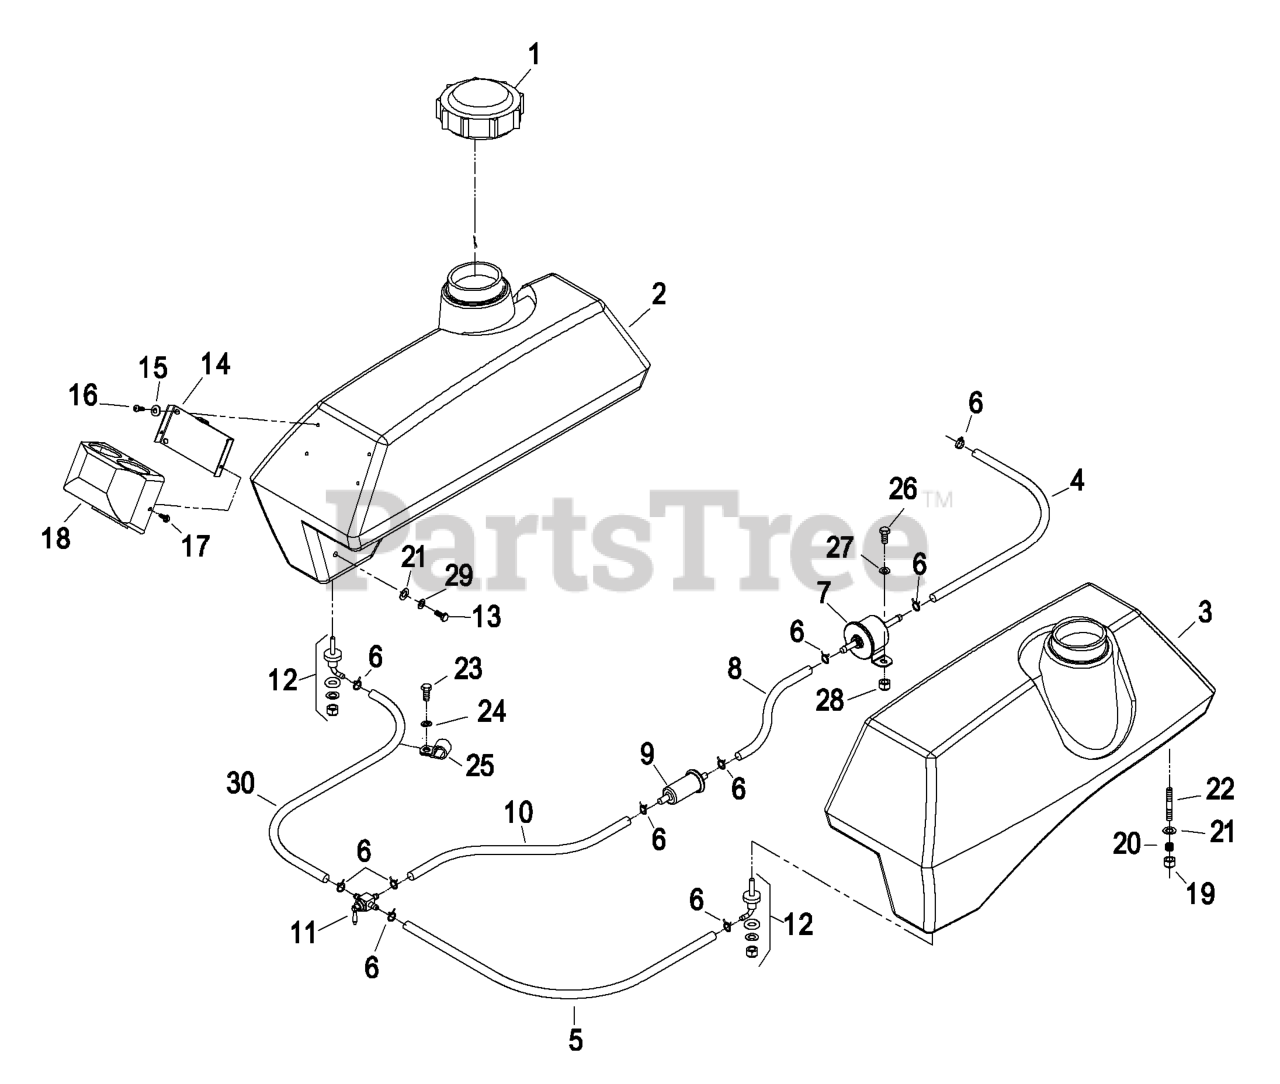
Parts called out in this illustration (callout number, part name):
2	KIT, FUEL TANK RH LZ LC
3	ASM, FUEL TANK LH LZ AC&L
4	HOSE-FUEL
5	HOSE-FUEL
7	P/N 49040-2065 Fuel Pump
8	HOSE-FUEL
9	P/N 49019-1055 Fuel Filter
10	HOSE-FUEL
11	VALVE-FUEL
12	FITTING-FUEL, BULKHEAD
13	SCREW-HH
14	BRACKET,GAUGE MOUNT
15	WASHER-SPRING
16	SCREW-PPH
18	COVER,GAUGES
19	NUT-LOCK, NI
20	SPRING-TANK, FUEL
21	WASHER-PLAIN
22	STUD
23	SCREW-HH
24	WASHER-LOCK
25	CLIP-LOOM
26	SCREW-HH
27	WASHER-FLAT
29	WASHER-LOCK
30	HOSE-FUEL
